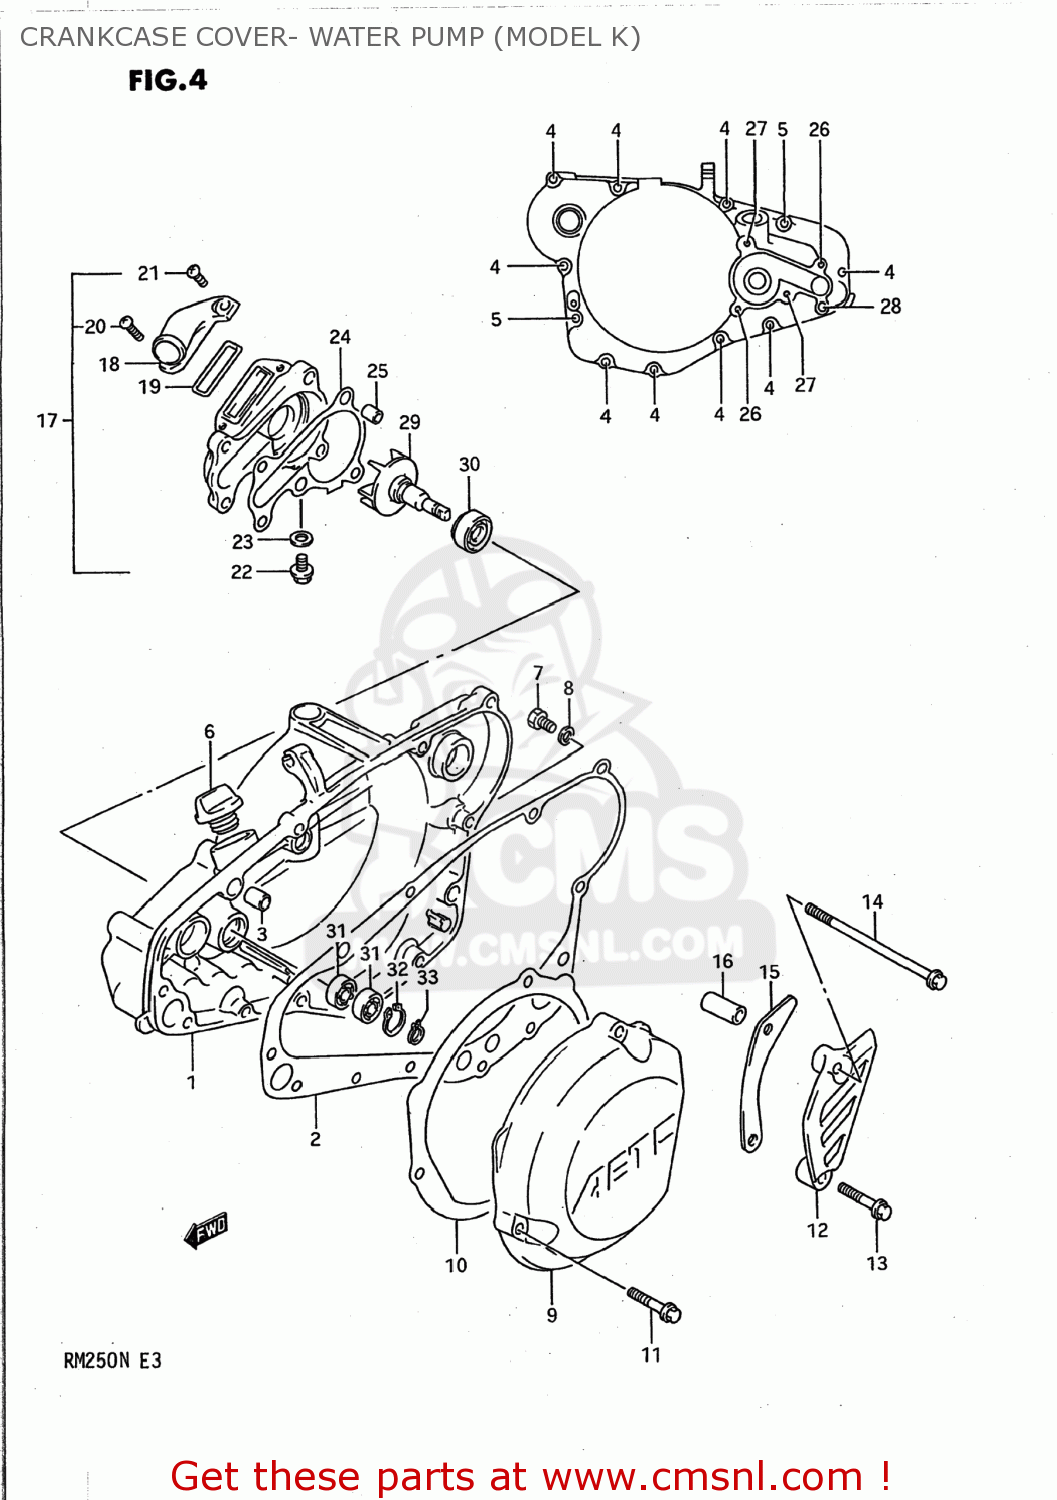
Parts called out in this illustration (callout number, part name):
1	COVER,CLUTCH
2	GASKET,CLUTCH COVER (NAS)
3	PIN
4	BOLT
5	BOLT
6	PLUG SET
7	SCREW(6X10)
8	GASKET(6.2X11X1).2 (NAS)
9	COVER
10	GASKET,MAGNETO COVER (NAS)
11	BOLT
12	COVER,SPROCKET
13	BOLT
14	BOLT 6X95
15	PLATE,FR CHAIN GUIDE(13T)
16	SPACER(6.5X10.5X25)
17	CASE ASSY,WATER PUMP
18	CONNECTOR
19	O RING
20	SCREW
21	SCREW
22	BOLT,BLEEDER
23	GASKET (NAS)
24	GASKET,WATER PUMP CASE (NAS)
25	PIN
26	BOLT
27	BOLT
28	BOLT
29	IMPELLER,WATER PUMP
30	SEAL,WATER PUMP OIL
31	BEARING
32	CIRCLIP
33	CIRCLIP
